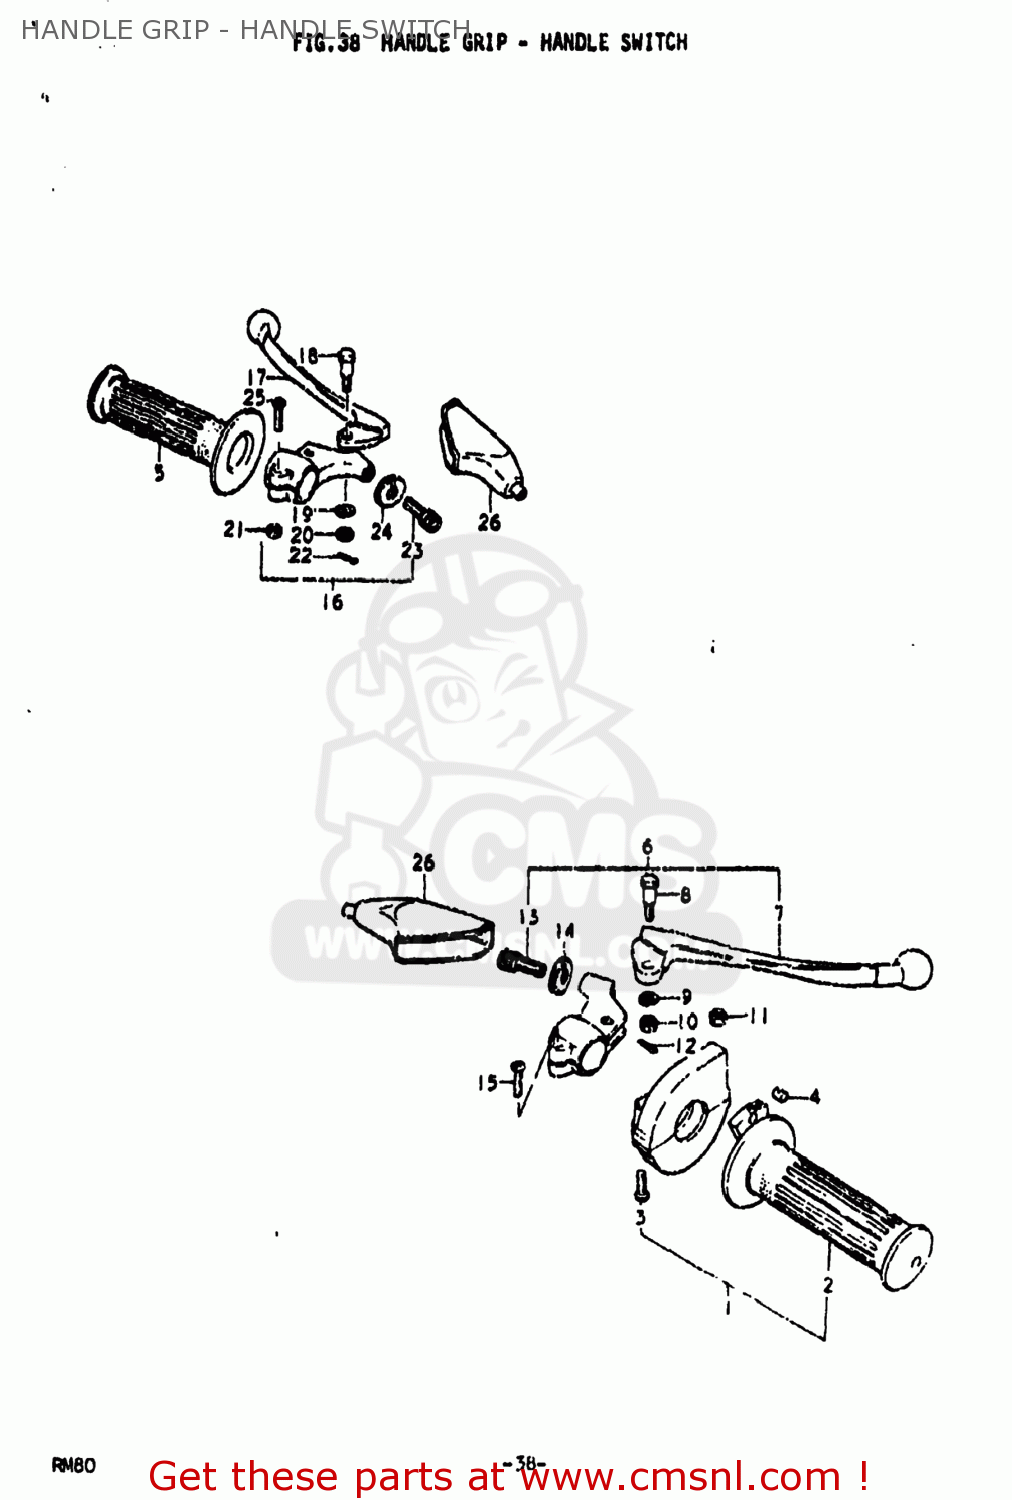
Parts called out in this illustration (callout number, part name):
1	GRIP ASSY,THROTTLE
2	GRIP,THROTTLE
3	SCREW
4	PIECE,THROTTLE END
5	GRIP,LEFT
6	LEVER ASSEMBLY,BRAKE
7	LEVER,BRAKE
8	BOLT,LEVER
9	LOCK WASHER
10	NUT,LEVER FITTNG
11	NUT 6MM
12	COTTER PIN
13	ADJUSTER,CABLE
14	NUT,CABLE ADJUSTER
15	SCREW
16	LEVER ASSEMBLY
17	LEVER,CLUTCH
18	BOLT,LEVER
19	LOCK WASHER
20	NUT,LEVER FITTNG
21	NUT 6MM
22	COTTER PIN
23	ADJUSTER,CABLE
24	NUT,CABLE ADJUSTER
25	SCREW
26	COVER,CLUTCH LEVER
